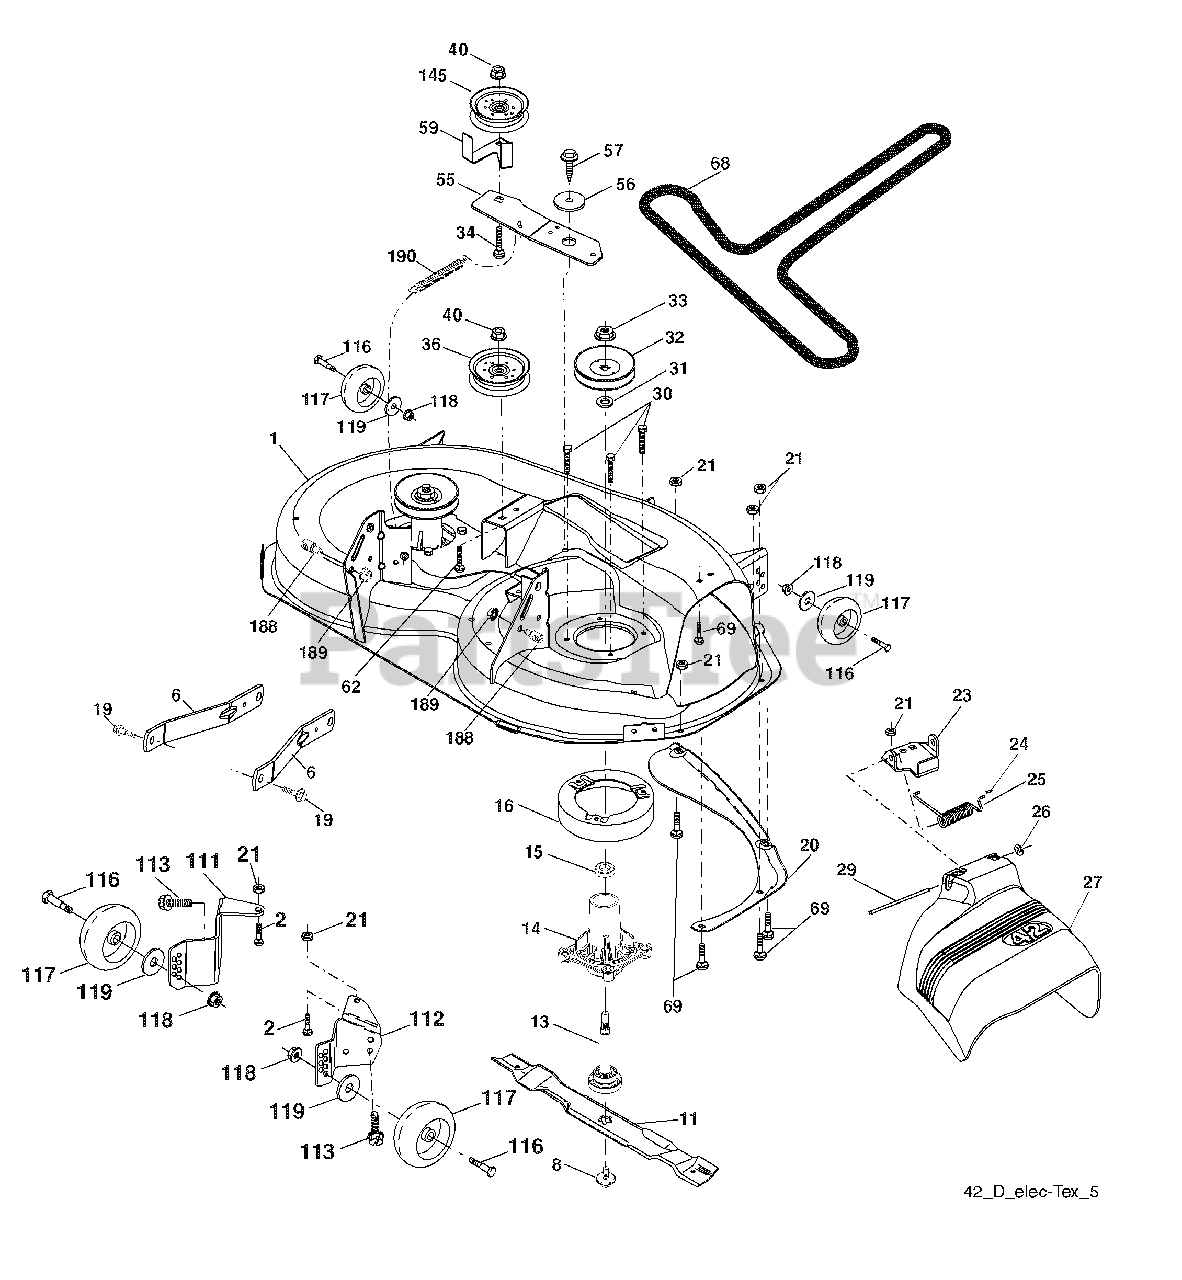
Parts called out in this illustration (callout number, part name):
1	Mower Deck Assembly, 42"
2	Bolt Rdhd Sqnk 5/16-18 unc x 3/4
6	Arm Susp. Rear
8	Bolt/Washer Asm 7/16-20 unf
11	Blade Mower 42" Hi-Lift
11	Blade, Mulching 42" Std
11	Blade Mulching 42" Premium
13	Shaft Assembly, Mandrel
14	Housing, Mandrel
15	Bearing, Ball, Mandrel
16	Stripper, Mandrel Deck
19	Bolt, Shoulder
20	Baffle, Vortex
21	Nut
23	Bracket, Deflector Mower 42"
24	Cap, Sleeve 80 x 112 Blk Mower
25	Spring, Torsion, Deflector
26	Nut, Push Phos & Oil
27	Shield, Deflector 42" Blk
29	Rod, Hinge 42" 6 75 W/G
30	Screw Thdrol
31	Washer, Spacer Mower Vented
32	Pulley, Mandrel
33	Nut, Toplock
34	Bolt Carr SH 3/8-16 x 1-1/2 Gr.5
36	Pulley, Idler, Flat
40	Nut Lock 3/8-16
55	Arm, Idler
56	Spacer, Retainer
57	Screw 3/8-16 x 1
59	Guard TUV Idler
62	Bolt Rdhd Sqnk 3/8-16 unc x 2
68	V-Belt, 42" Mower
69	Bolt, Carriage 5/16-18 x 5/8
111	Bracket Wh Gauge LH
112	Bracket Wh Gauge RH
113	Screw 5/16-18
116	Bolt, Shoulder
117	Wheel, Gauge
118	Nut Centerlock 3/8-16
119	Washer 3/8 x 7/8 x 14
145	Pulley Idler Flat
188	Stud Fastner W/D Anti-Rotation
189	Nut Lock Hex Flange 5/16-18
190	Spring Mower Drive
190	Mandrel Assembly
190	Replacement Mower, Complete
